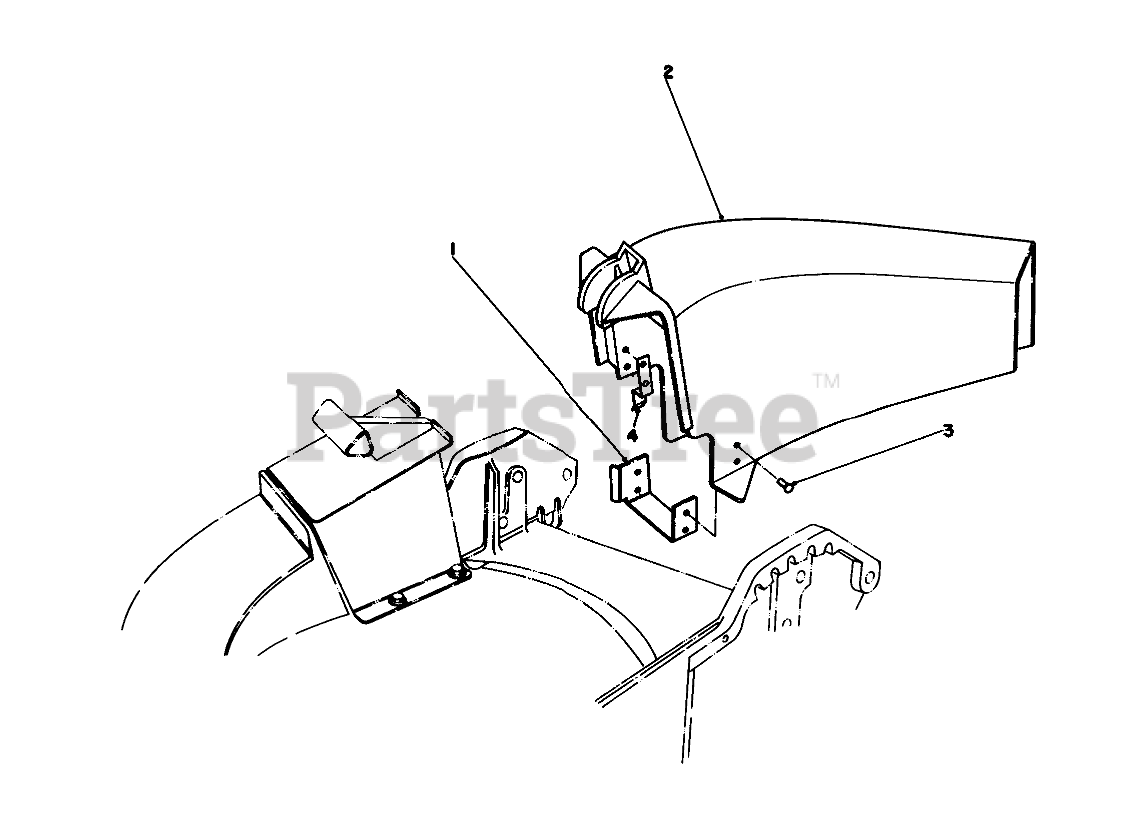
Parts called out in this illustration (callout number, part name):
1	CHUTE BRACKET
2	Chute Discharae
3	RIVET
4	CHUTE TAB
